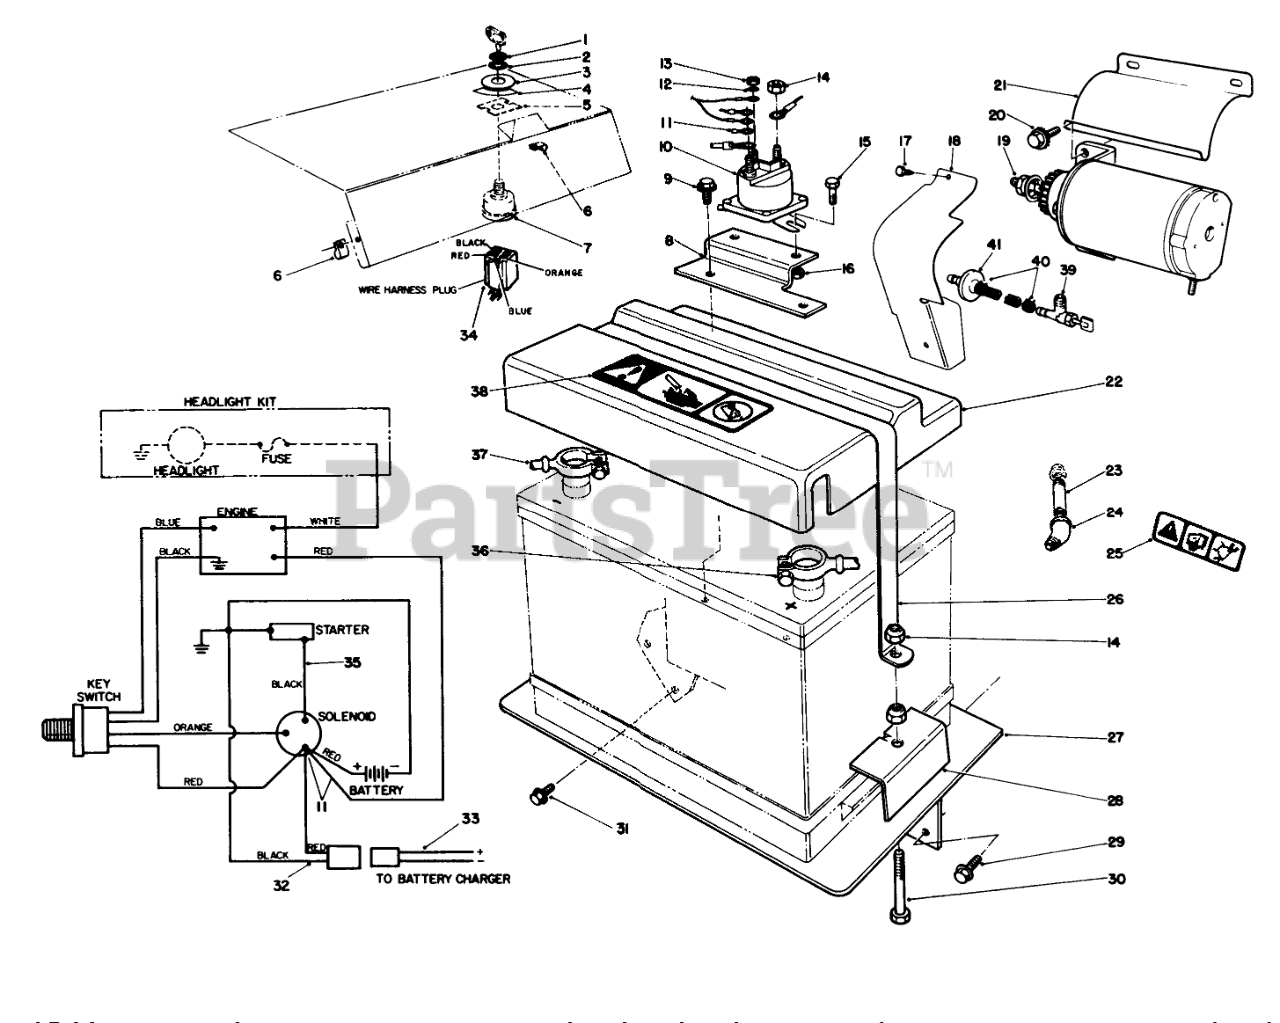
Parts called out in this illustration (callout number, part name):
1	NUT-HH
2	WASHER-TOOTH, INTERNAL
3	WASHER
4	DECAL
5	ADAPTER
6	Clip-Wire
7	Switch-Starter (Incl. Ref. #1-2)
8	Plate-Solenoid
9	SCREW-HWH
10	SOLENOID
11	RING TONGUE TERMINAL
12	WASHER-LOCK, INT
13	NUT-HEX
14	NUT-LOCK, NI
15	SCREW-HH
16	NUT-LOCK, NI
17	Screw
18	Shield-Pinion
19	Starter Motor Ass-y
20	Crew
21	Shield-Dip
22	BATTERY COVER
23	NIPPLE 3/8NPTX 1.50
24	ELBOW
25	DECAL-WARNING
26	Strap Battery
27	Plate-Battery
28	BATTERY CLAMP
29	SCREW-HHF
30	SCREW-HH
31	SCREW-HHF
32	MALE WIRE ASM
33	FEMALE WIRE ASM
34	WIRE HARNESS
35	STRT MTR-SOLNOID WIRE
36	BATT-SOLENOID CABLE
37	KEY-SHIFT
38	DECAL
39	Valve-Fuel Tank
41	Filter
